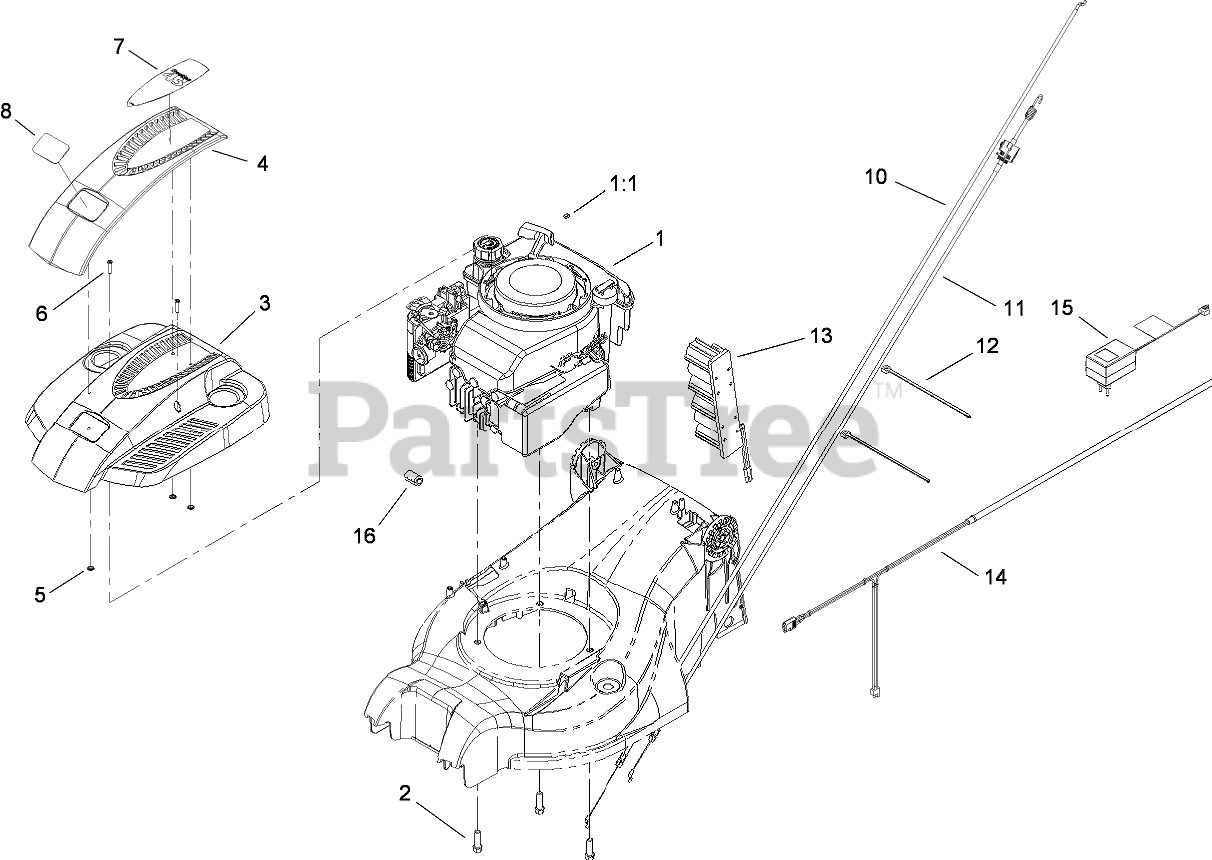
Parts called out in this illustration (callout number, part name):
1:1	STOP-ROPE
2	SCREW-TAPTITE
3	SHROUD-ENGINE
4	COVER-SHROUD
5	CLIP-PUSH
6	SCREW-PPH
8	DECAL
10	CABLE-BRAKE
11	CABLE-TRACTION
12	TIE-CABLE
13	BATTERY
14	HARNESS-WIRING
15	CHARGER-EUROPEAN, 12V DC
16	FERRITE-SNAP ON
